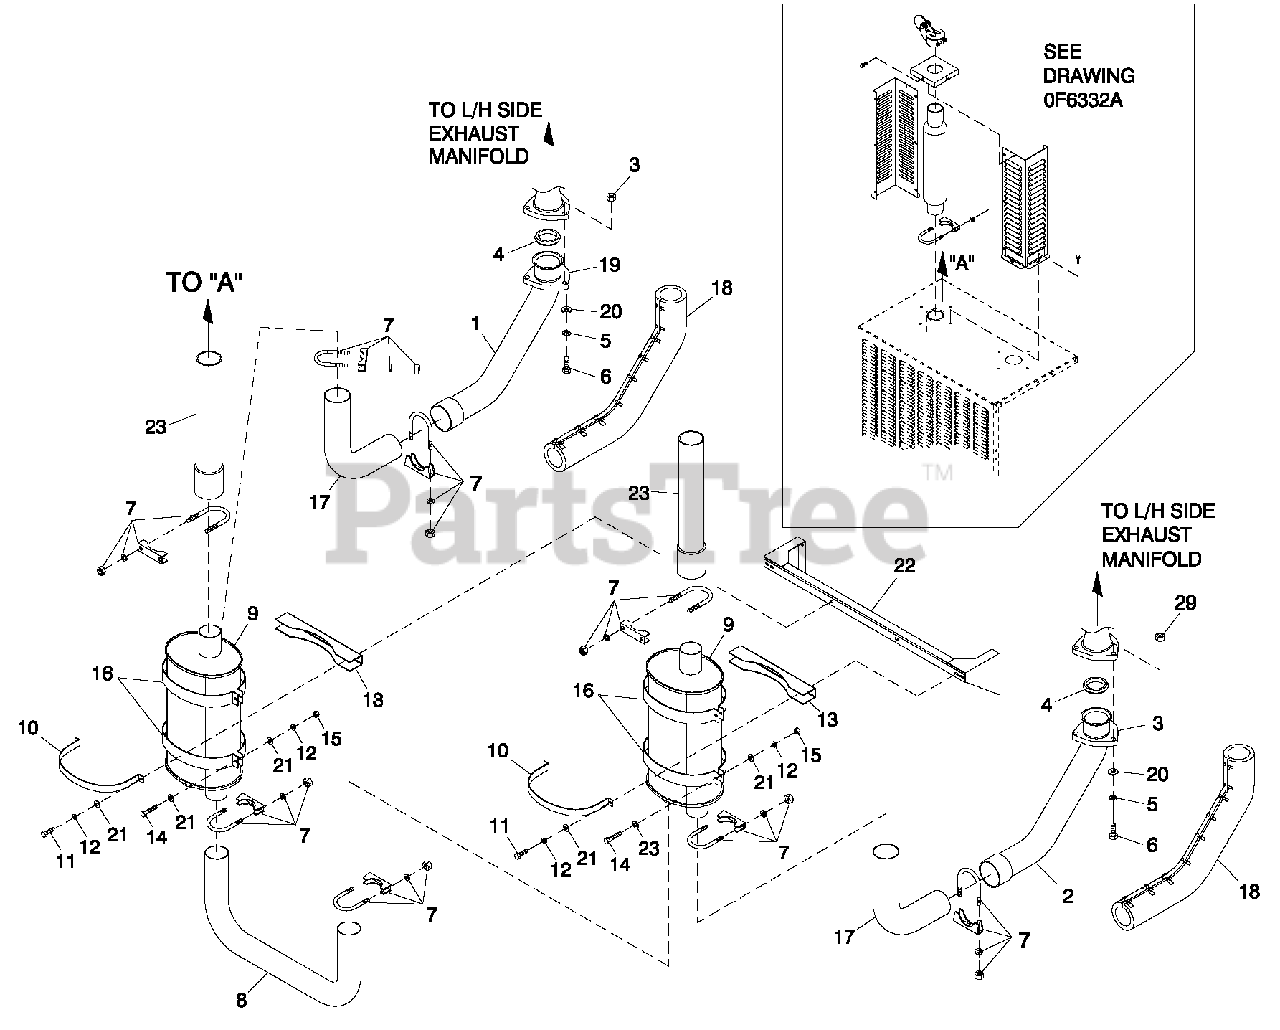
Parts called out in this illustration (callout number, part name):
1	PIPE EXH MAN RIH 6.8L GIB CPL (6.8L C5)
2	PIPE EXH MAN LIH 6.8L GIB CPL (6.8L C5)
3	NUT HEX M10-1.5 SS
4	RING GASKET 2.5 DIA
5	WASHER LOCK M10SS
6	SCREW HHC M10-1.5 X 50 SS FTH
7	BOLT U3I8-16X 2.62
8	PIPE EXHAUST CROSSOVER
9	MUFFLER 7" X 9" X 25" (2) 2.5" INI2.5" OUT
10	MUFFLER STRAP
11	SCREW HWHT M6-1 X 16 N WA Z/JS
12	WASHER LOCK M6-1I4
13	MUFFLER BRACKET STIFFENER
14	SCREW HHC M6-1.0 X 35 G8.8 BLK
15	NUT HEX M6X 1.0 G8YEL CHR
16	MUFFLER STRAP UPPERILOWER
17	PIPE ELBOW EXHAUST MUFFLER
18	EXHAUST BLANKET 900MM LONG (6.8L C5)
19	FLANGE EXHAUST
20	WASHER FLAT 3I8SS
21	WASHER FLAT 1I4-M6 ZINC
22	BRACKET MUFFLER
23	EXHAUST OUTLET PIPE CPL
